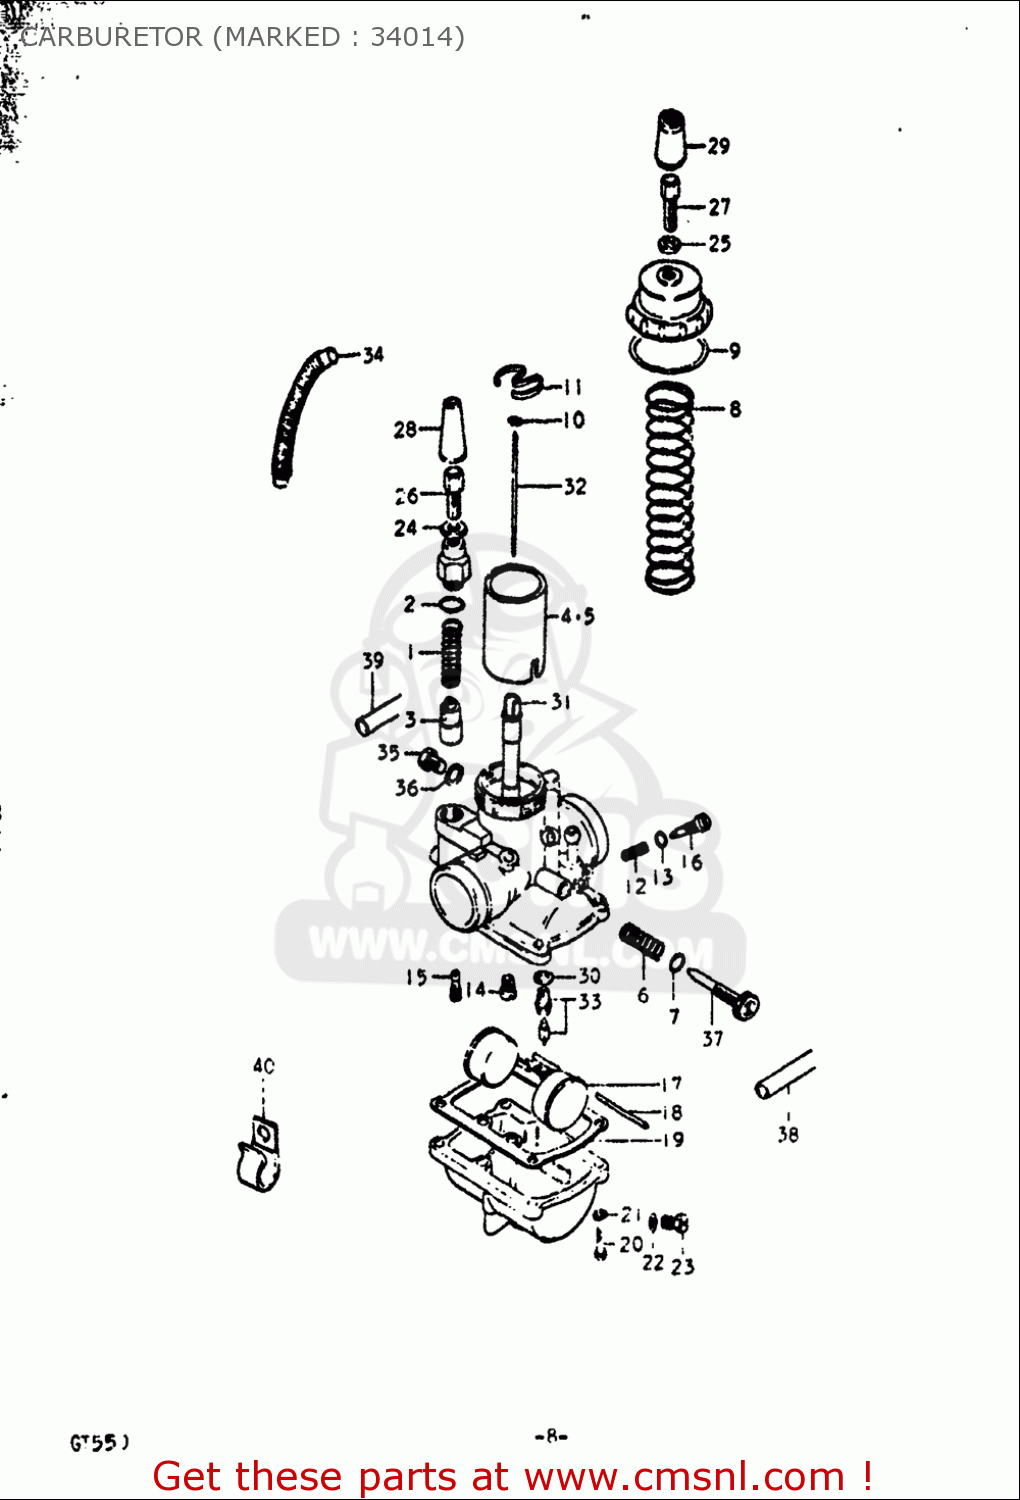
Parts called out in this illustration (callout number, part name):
1	SPRING
3	PLUNGER,STARTER
6	SPRING,THROTTLE SCREW
7	O RING
10	CLIP
11	SEAT,THROTTLE VALVE SPRING
12	SPRING
13	O RING
14	JET,MAIN(95)
15	JET,PILOT(27.5)
16	SCREW,PILOT AIR
18	PIN,FLOAT
19	GASKET,FLOAT CHAMBER (NAS)
20	SCREW 4X16
21	WASHER,LOCK
22	GASKET,DRAIN,PLUG (NAS)
23	PLUG
25	NUT
26	ADJUSTER,CABLE
28	CAP,RUBBER
30	GASKET,VALVE SEAT (NAS)
33	VALVE ASSY,NEEDLE
35	BOLT
36	GASKET,THRO VALVE INSPECTION (NAS)
37	ADJUSTER
